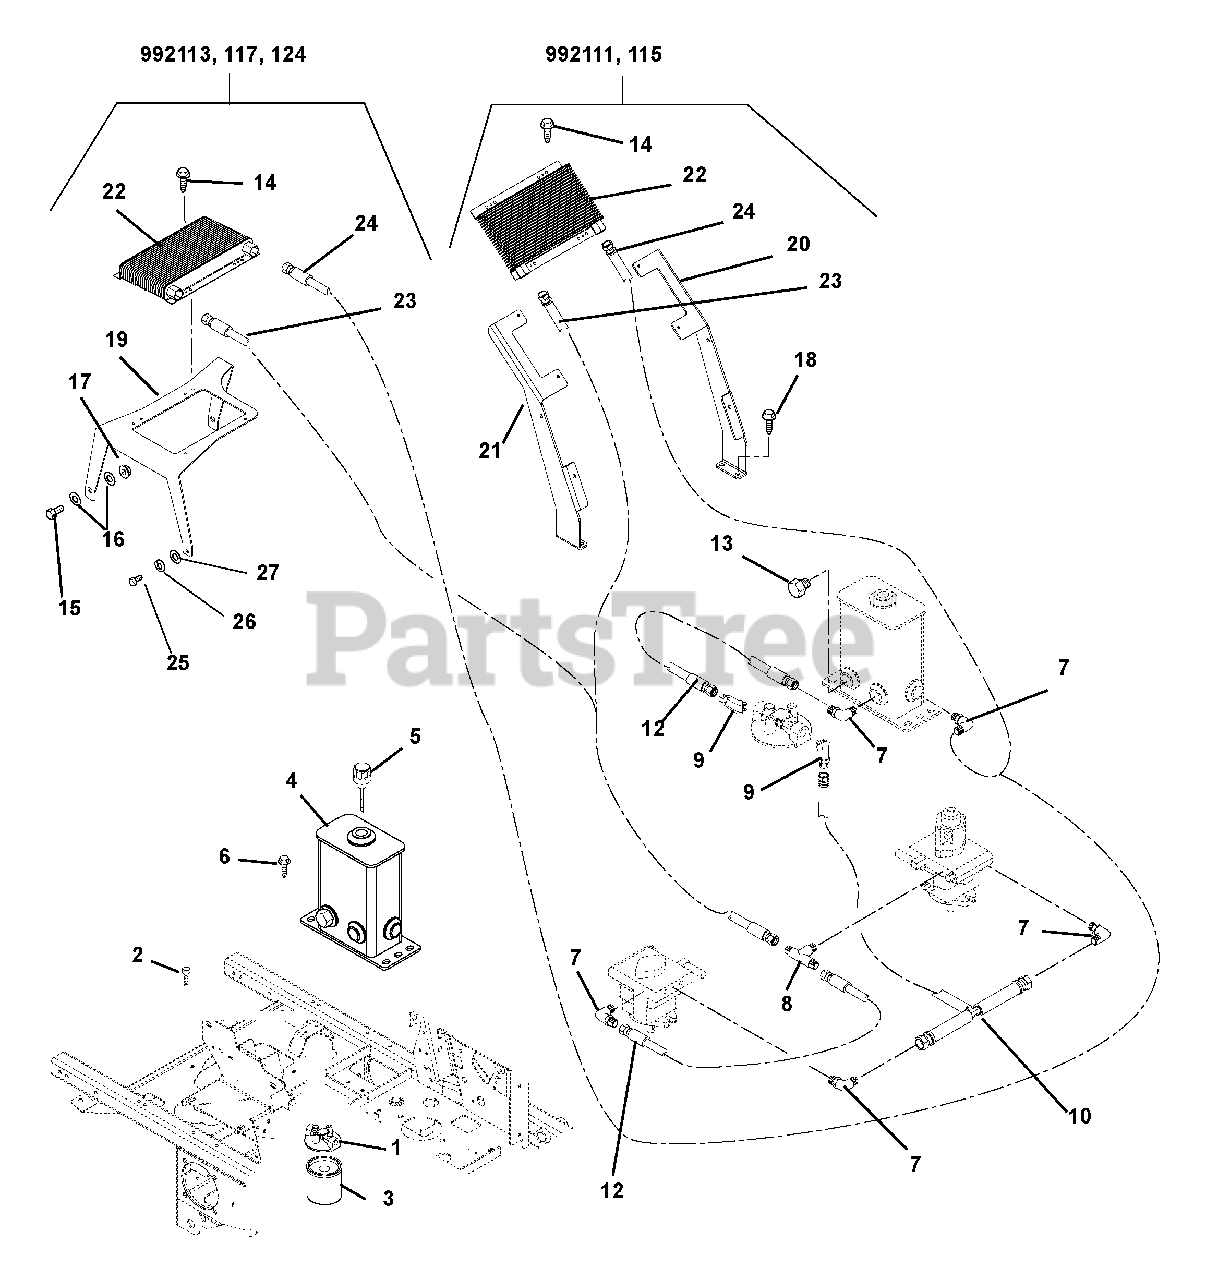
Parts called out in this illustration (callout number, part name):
1	Head, Filter
2	Bolt, Hex .25-20 x .50 Epoxy Grade 5
3	Oil Filter
4	Weldment, Hydraulic Tank
5	Hydraulic Tank Dipstick
6	Screw, Tapping .38-16 x .75 Hex Washer Head
7	Fitting, Hydraulic, 90 Degree Elbow, Steel M8F-M80
8	Fitting, Hydraulic Tee M80-M80-M80
9	Fitting, Hydraulic 45° M80-M120
10	Hose, Tee Assembly, .50
11	Hose, Hydraulic
12	Hose, Hydraulic
13	Plug, Hex, .75-16 O-Ring
14	Screw-Tapping .25-20 x .375 Hex Washer Head
15	Bolt-Hex .50-13 x .75 Grade 5 (992113, 117, 124)
16	Washer-Flat-Steel .531 x 1.06 x .095 (992113, 117, 124)
17	Nut .50-13 Nyloc Flange (992113, 117, 124)
18	Screw-Tapping .38-16 x .50 Hex Washer Head (992111, 115)
19	Bracket-Oil Cooler-Kawasaki Liquid Cooled (992113, 117, 124)
20	Bracket, Vertical, Air Cooler Mounting-Left Hand (992111, 115)
21	Bracket, Vertical, Air Cooler Mounting-Right Hand (992111, 115)
22	Cooler, Oil Long MFG# 703
23	Hose, Hydraulic .50-24-0K M08NO-F08F9 (992111, 115)
23	Hose, Hydraulic .50-31-0K M08NO-F08FO (992113, 117, 124)
24	Hose, Hydraulic .50-24-0K M08NO-F08F9 (992111, 115)
24	Hose, Hydraulic .50-25-0K M08N0-F08FO (992113, 117, 124)
25	Bolt-Hex M6-1.00 x 20 (992113, 117, 124)
26	Washer-Lock .25 x .062 (992113, 117, 124)
27	Washer-Flat-Steel .281 x .62 x .065 (992113, 117, 124)
